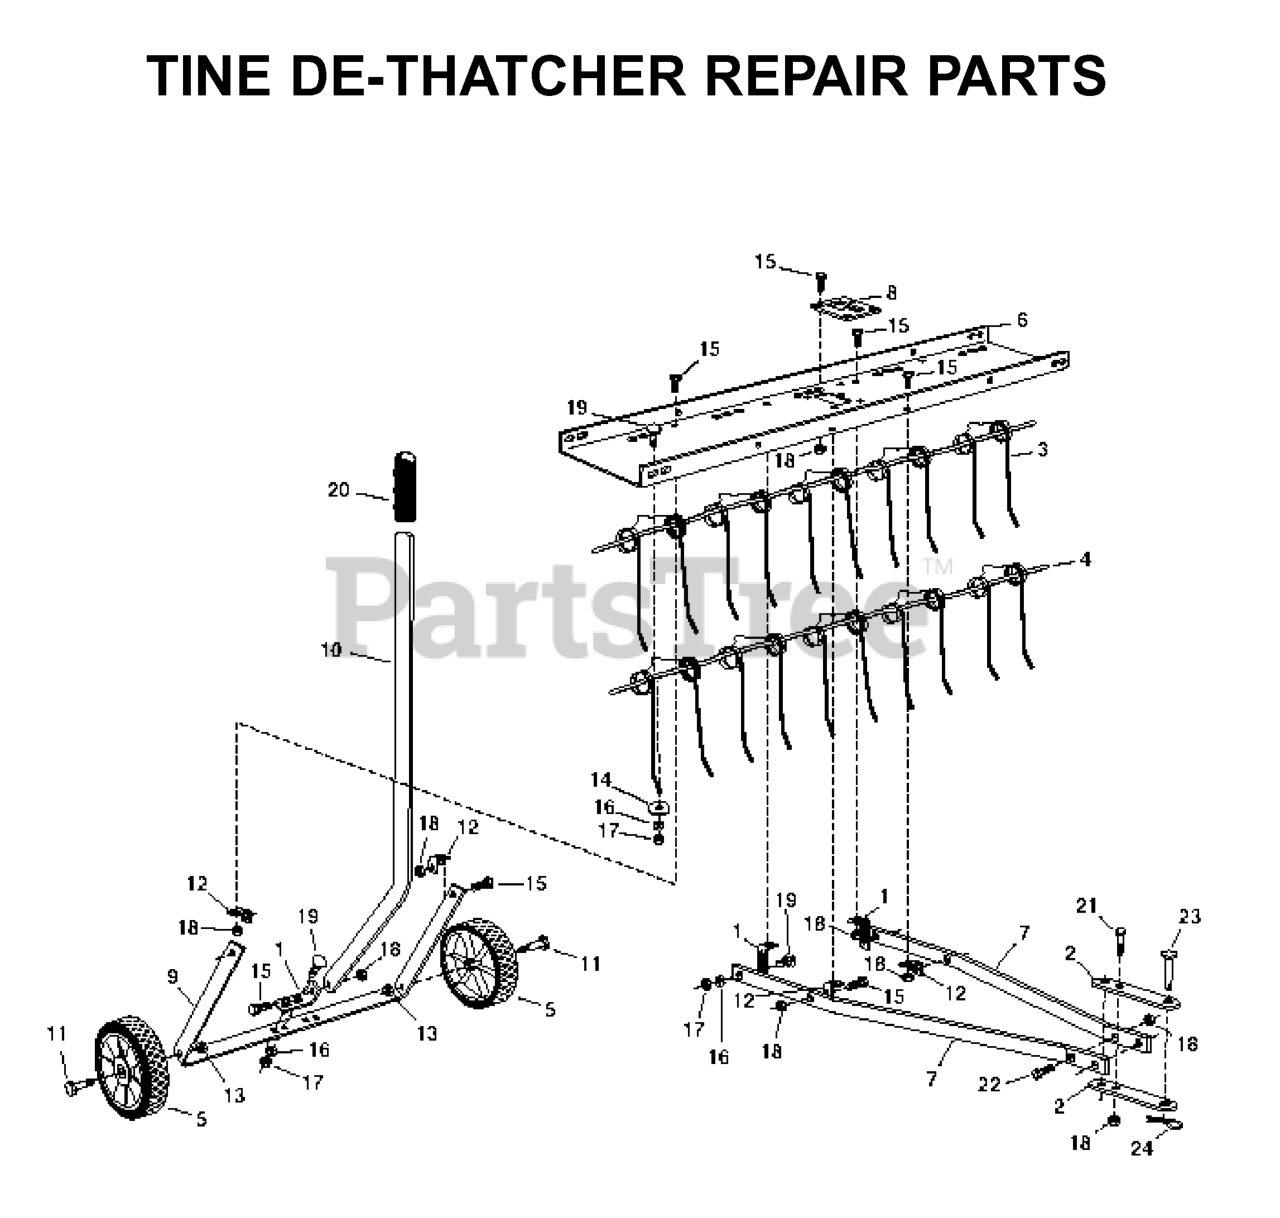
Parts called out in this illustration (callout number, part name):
2	BRACKET THATCHER
3	SPRING TINE
14	WASHER
15	BOLT.FIN.HEX.5/16-18X3/4
20	Rubber Grip
21	Bolt Fin Hex 5/16 - 18 Unc x 2 Gr. 2
